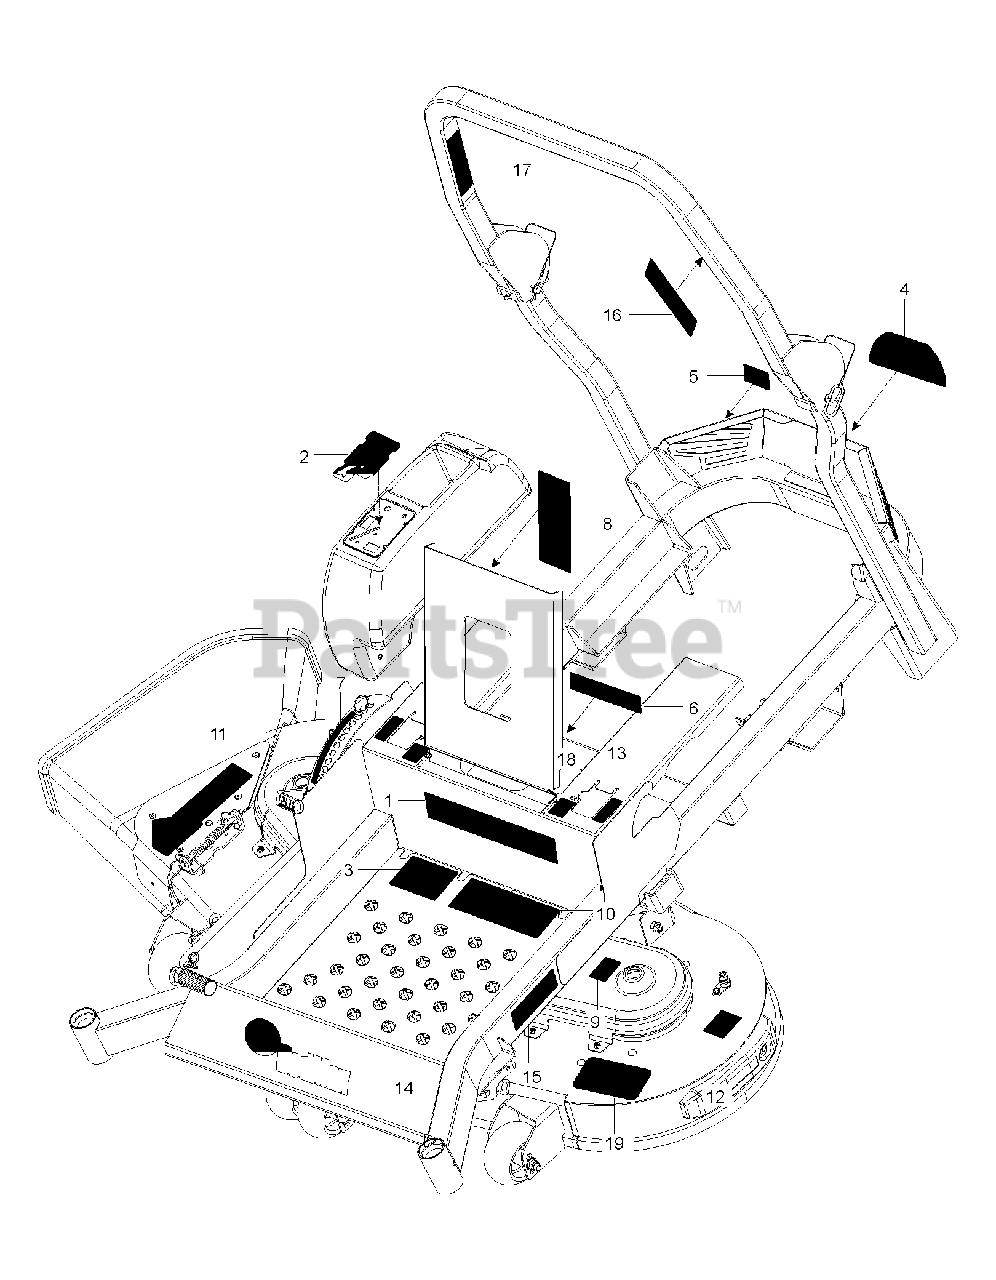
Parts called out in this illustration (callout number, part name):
1	DECAL ZTR MODEL NUMBER DECAL.Z
2	DECAL CTRL PANEL GRAPHIC DECAL
3	DECAL ZTR STARTING DECAL
4	DECAL ZTR BRAND GRAPHIC DECAL.
5	DECAL, BELT DRIVE
6	EURO DECAL-BATTERY WARNIN6
7	Decal, ZTR Instruction Graphic
8	DECAL, SERVICE
9	DECAL.DECK.CLEARCUT.NOSTEP
10	DECAL ZTR WARNING DECAL DECAL.
11	DECAL DECK WARNING GRAPHIC DEC
12	Deck Decal, 54"
13	DECAL.ZTR.MTNCONTROL.2015.PPRO
14	DECAL ZTR BRAND GRAPHIC DECAL.
15	DECAL ZTR SIDE RAIL GRAPHIC DE
16	DECAL ROPS
17	DECAL, ROPS, WARNING
18	DECAL.ZTR.TRACKING.GRAPHIC
19	FOOT PAD
